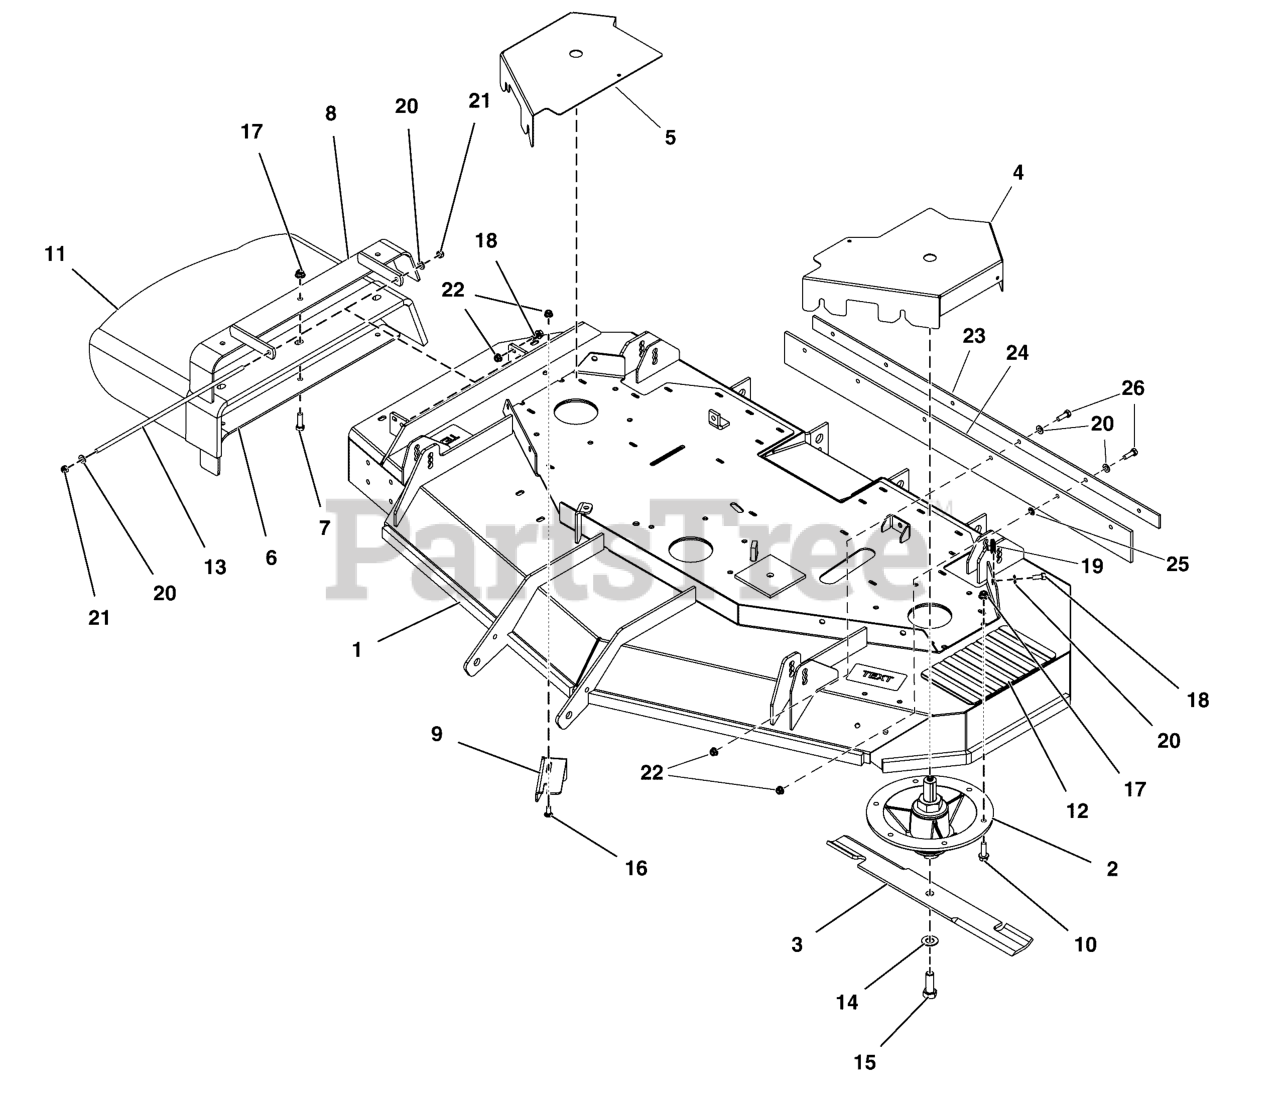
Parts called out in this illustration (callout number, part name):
1	DECK SHELL W/ DECALS, LMTD EDTN 61
2	SPINDLE ASSEMBLY
3	BLADE, 21 X .25 X 2.5, 1 X 3.5 (SET OF 3)
4	GUARD, Belt
5	GUARD, Belt
6	PLATE, Support
7	BOLT, Carriage, 3/8-16 X 1 1/2, GR5
8	FRAME, Chute
10	BOLT, Flange, 3/8-16 X 1 1/4
11	CHUTE, RUBBER DISCHARGE (5104442)
12	SAFETY WALK, 9.75 X 6.00
13	MOUNT, Chute
14	WASHER, Blade Bolt, 9/16"
15	BOLT, 5/8-11 X 1 3/4, GR 8
16	BOLT, 5/16-18 X 3/4, CARRIAGE, GD5, CZ
17	NUT, Hex Flange, Nylock, 3/8-16
18	CAPSCREW, Hex Head, 5/16-18 x 3/4
19	CLIP, BODY , 5/16-18 FOR 7 GA.
20	WASHER, 5/16, Flat SAE, Zinc/Clear
21	NUT, Hex Lock, Nylon, 5/16-24
22	NUT, Flange Nylock, 5/16-18
23	PLATE SUPPORT
24	FLAP STRIPER 61 DEC
25	NUT, Push On, 5/16
26	CAPSCREW, Hex Head, 5/16-18 x 1
